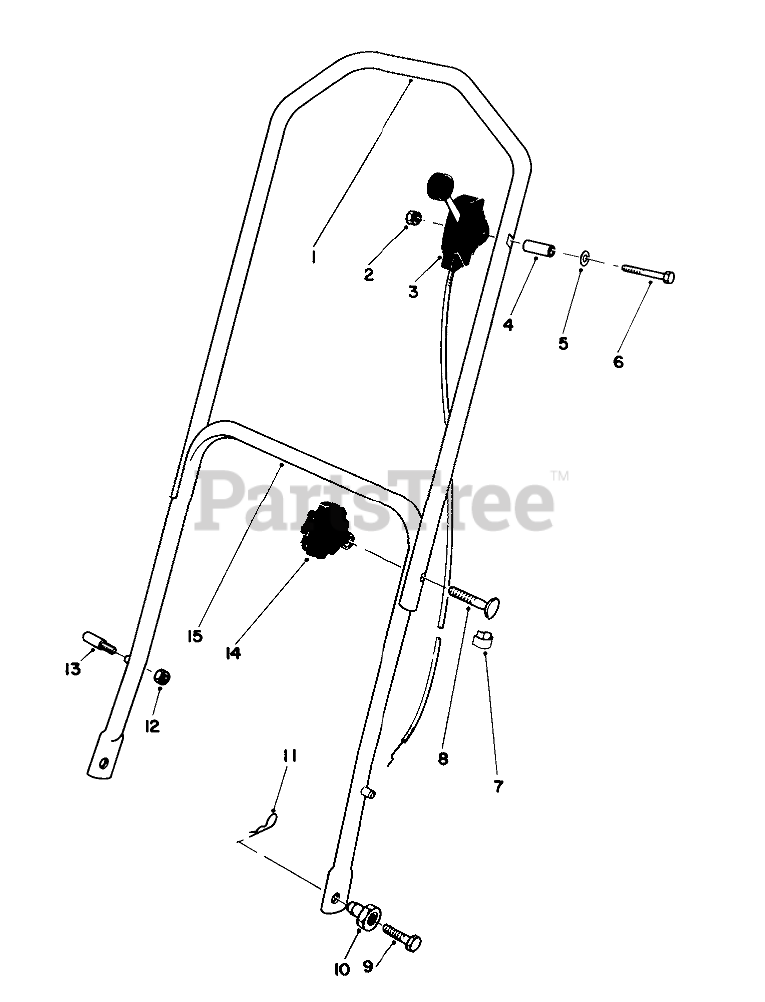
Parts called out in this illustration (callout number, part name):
1	Handle-Upper
2	NUT-LOCK, NI
3	SERVICE THROTTLE CONTRO
4	Spacer
5	WASHER
6	SCREW-HH
8	5/16-18 X 2 HNDLE SCREW
9	SCREW-HH
10	HANDLE PIVOT NUT
11	PIN-COTTER, HAIR
12	NUT-LOCK, NI
13	HANDLE PIN
15	LOWER HANDLE ASM
